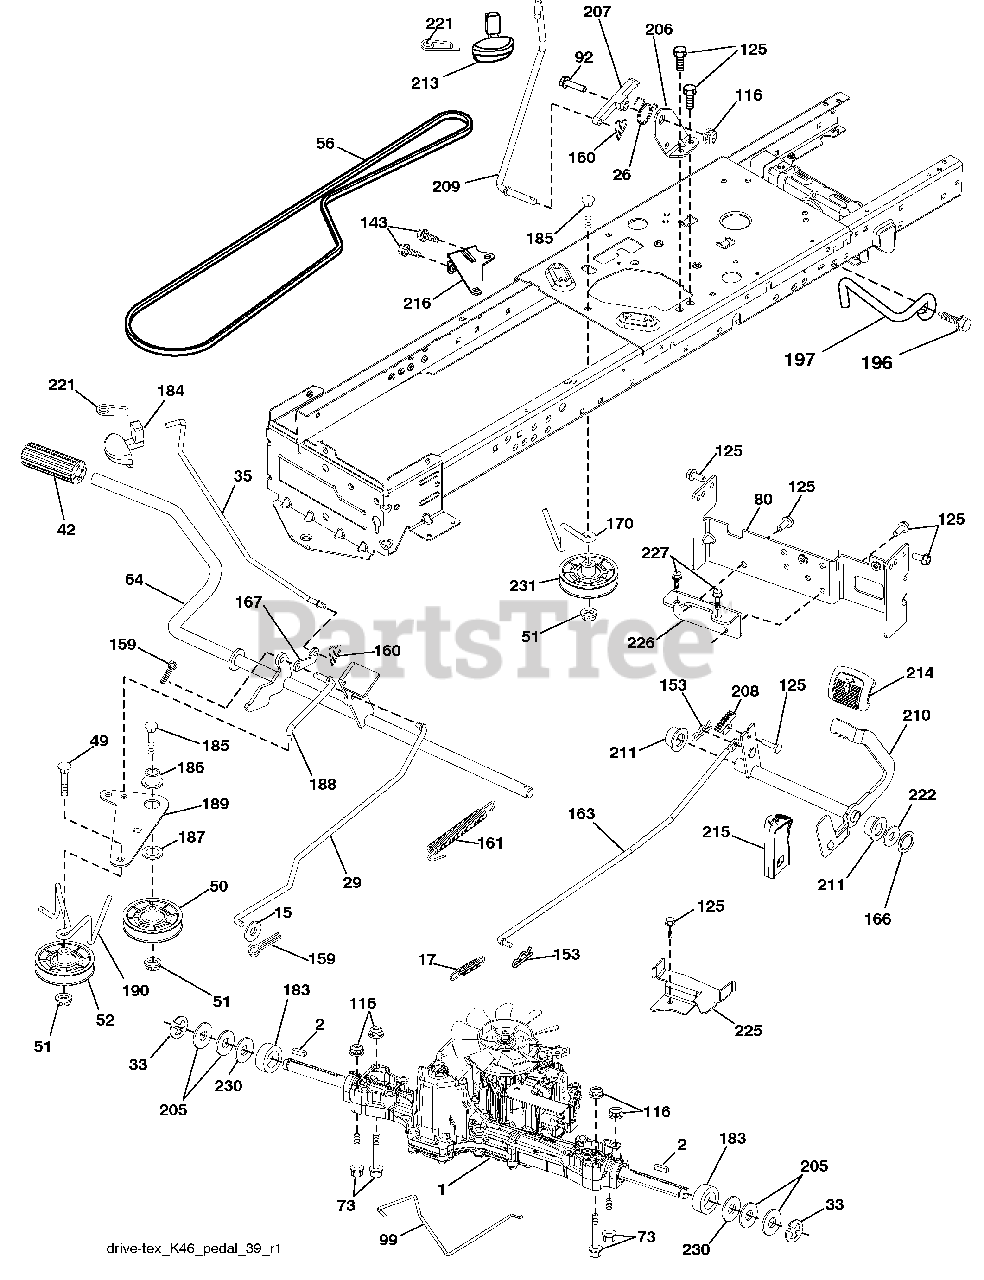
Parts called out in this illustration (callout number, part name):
15	Washer 13/32 x 13/16 x 16 Ga.
17	Spring, Brake
26	Spring Return Cruise
29	Rod, Brake
35	Rod, Brake, Park
42	Cover, Foot Pedal
50	Pulley Idler Flat
51	Lock Nut 3/8-16
52	Idler V-Groove 910" Offset
56	V-Belt, Drive
64	Shaft Asm. Pedal Brake Control
73	Bolt 5/16-18 Gr. 5
80	Strap Torque
92	Bolt Fin Hex 5/16-18 unc x 1.25
99	Spring Rod Bypass
116	Nut Lock Hex Flange 5/16-18
125	Screw 5/16-18 x 3/4
143	Screw Thdrol 5/16-18 x 1/2
153	Retainer Spring
159	Pin Cotter 1/8 x 3/4
160	Retainer Clip
161	Spring, Return, Clutch
163	Rod Pedal Control
166	Nut Push .625
167	Latch Brake Parking
170	Keeper Belt Centerspan
183	Spacer Split
184	Handle Parking Brake
185	Bolt 3/8 - 16 x 2-3/4 Gr. 5
186	Spacer Retainer
187	Washer
188	Link Clutch Ground Drive
189	Bellcrank Ground Drive
190	Keeper Bellcrank Ground Drive
196	Screw 3/8-16 x 1
197	Bracket Clutch Anti-Rotation
206	Bracket Mount Latch Cruise
207	Latch Control Cruise
208	Gear Sector Control Cruise
209	Rod Control Cruise
210	Rocker Asm. Pedal Control
211	Bearing Nylon
213	Knob Control Cruise
214	Pedal Forward
215	Pedal Reverse
216	Bracket Pulley Idler
221	Retainer Spring Clip Handle
222	Washer 21/32 x 1-1/4 x 10 Ga.
225	Keeper Belt Trans.
226	Bracket Mount Touque
227	Screw Thdrol 5/16-18 x 3/4
231	Idler V-Groove Pulley
